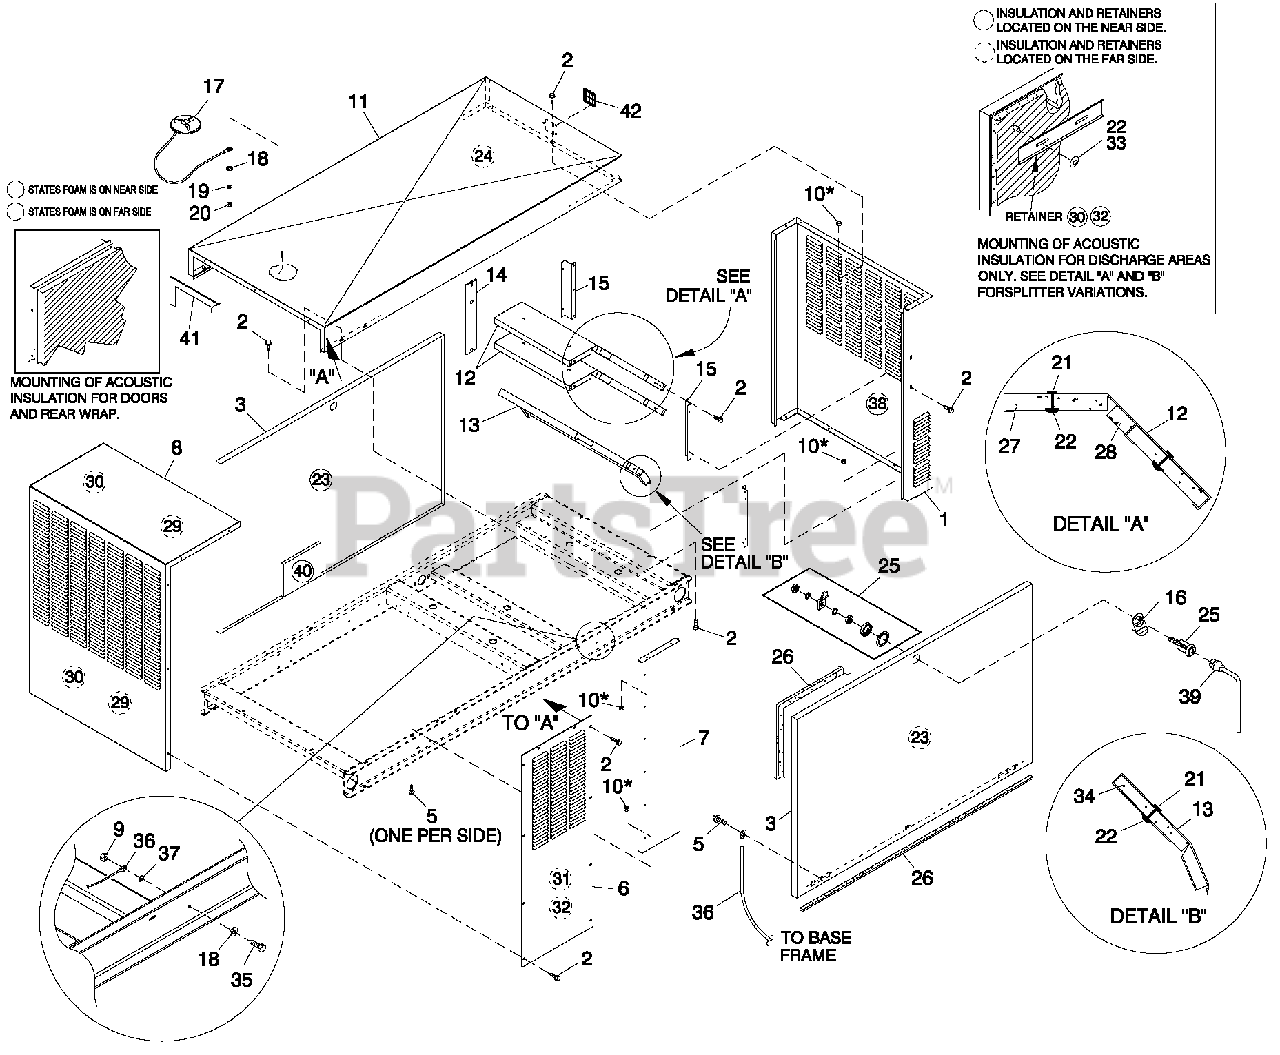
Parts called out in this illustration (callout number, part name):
1	REAR WRAP C2 CPL
2	SCREW THF M6-1 X 16 N WA Z/JS
3	DOOR C2
4	RIVET POP .1875 X .450 SS
5	SCREW TH-FRM M6 W/CAP SHKPRFW
6	DISCHARGE DUCT LH & RH SI DE C2
7	FRONT CORNERS C2
8	DISCHARGE CENTER DUCT C2
9	NUT HEX M6X 1.0 G8YEL CHR
10	NUT HEX LOCK M6-1.0 SS NY INS
11	ROOF C2
12	SLITTER C4
13	SPLITTER LOWER C4
14	SPLITTER STINGER C2
15	SUPPORT SPLITTER LH C2
16	TAB PULL
17	ASSEMBLY COVER ACCESS
18	WASHER FLAT 1/4-M6 ZINC
19	WASHER LOCK M6-1/4
20	NUT HEX 1/4-20 STEEL
21	INSULATION RETAINMENT HANGER
22	WASHER SELF LOCKING DOME #4-40
23	INSULATION DOOR C2
24	INSULATION ROOFTOP
25	VISE-ACTION LATCH SLOTTE D CIR
26	GASKET EXTRUDE DTRIM (328" LG)
27	INSULATION SPLITTER
28	INSULATION SPLITTER
29	INSULATION DUCT
30	RETAINER INSULATION (820)
31	INSULATION DUCT SI DES
32	RETAINER INSULATION (450)
33	WASHER SELF LOCKING DOME #8-32
34	INSULATION LOWER SPLITTER
35	SCREW HHC M6-1.0X 20 G8.8
36	ASSY WIRE 14AWG 34.8" GRN/YEL
37	WASHER SHAKEPROOF INT 1/4
38	INSULATION REAR WRAP
39	KEY VISE-ACTION LATCH SLOT CIR
40	FOAM 300 X 300 THERMAL ACO (APPLIES TO 4.2L UNITS ONLY)
41	STRIP SEALANT 1/8 X 1 (44.52"LG)
42	RF COVER PLATE-PLASTIC-BISQUE
